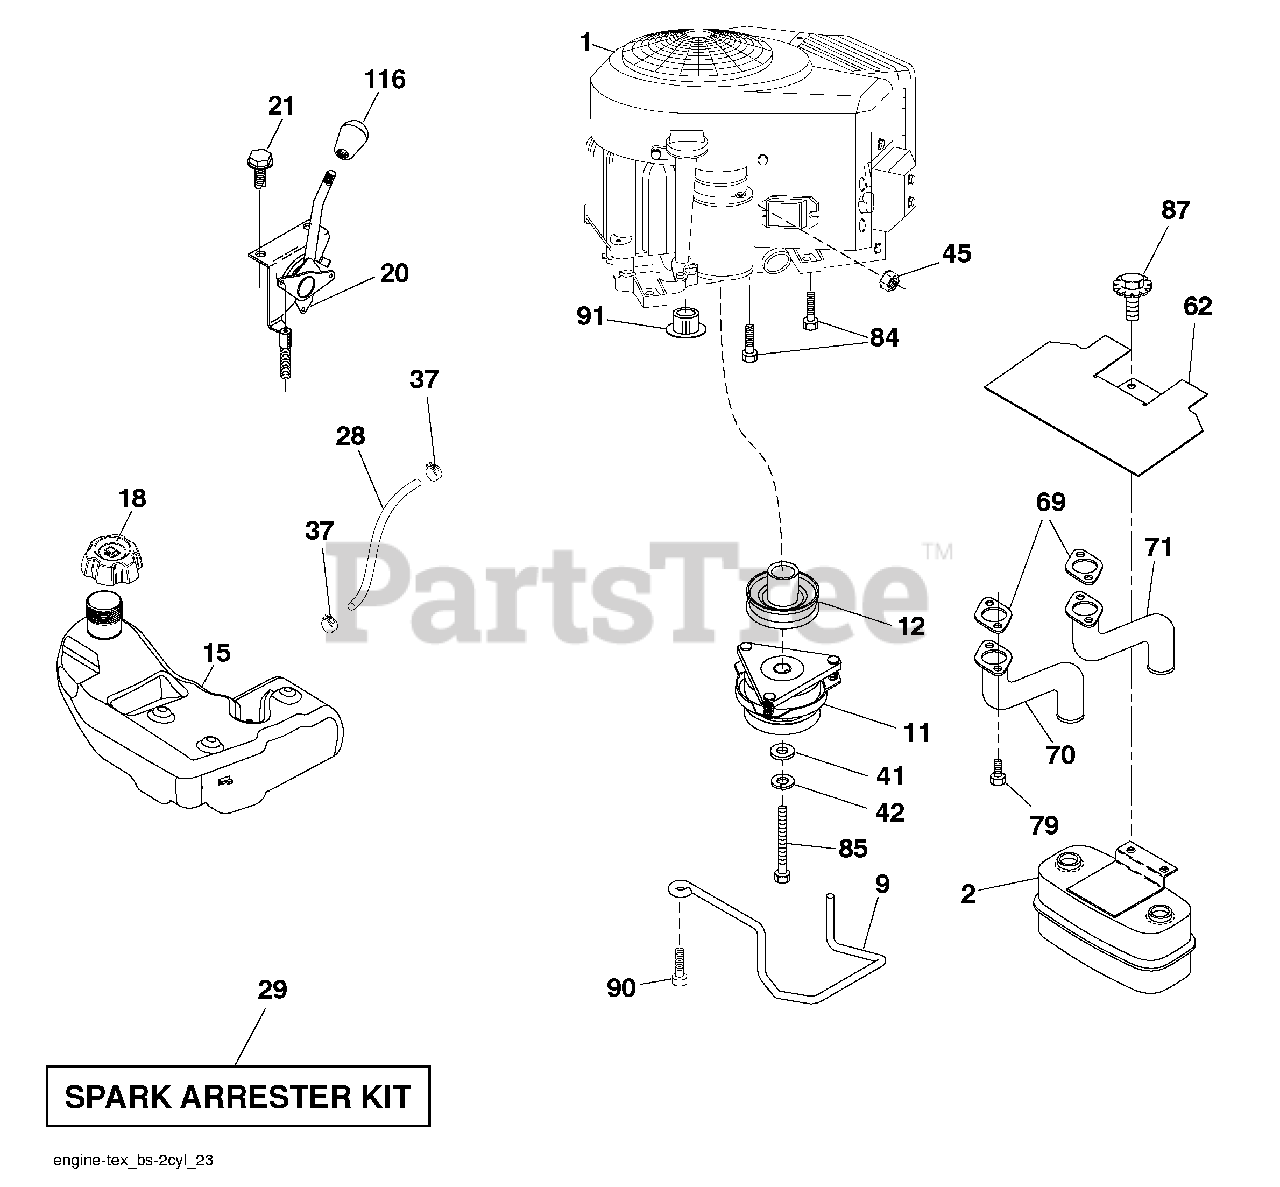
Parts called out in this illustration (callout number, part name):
9	Keeper Belt Engine
11	Clutch
12	Pulley Engine
15	Tank Fuel
18	Cap Asm Fuel
20	Control Throttle/Choke
21	Screw #10 X .750 Bos Thread
28	Fuel Line
29	Spark Arrester Kit
37	Clamp Hose
41	Washer 1-1/2 Od X 15/32 Id X .250
42	Washer Lock 7/16
45	Nut Keps Hex 1/4-20 Unc
62	Heat Shield
70	Exhaust Tube Lh
71	Exhaust Tube Rh
79	Screw Socket Head 5/16-18 X1
84	Screw 3/8-16 X 1-1/4
85	Bolt Hex 7/16-20 X 4 X Gr. 5-1.5 Thr
87	Bolt 5/16-18 Unc X 3/4 W/Sems
90	Screw 3/8-16 X 1
116	Knob Soft Touch
